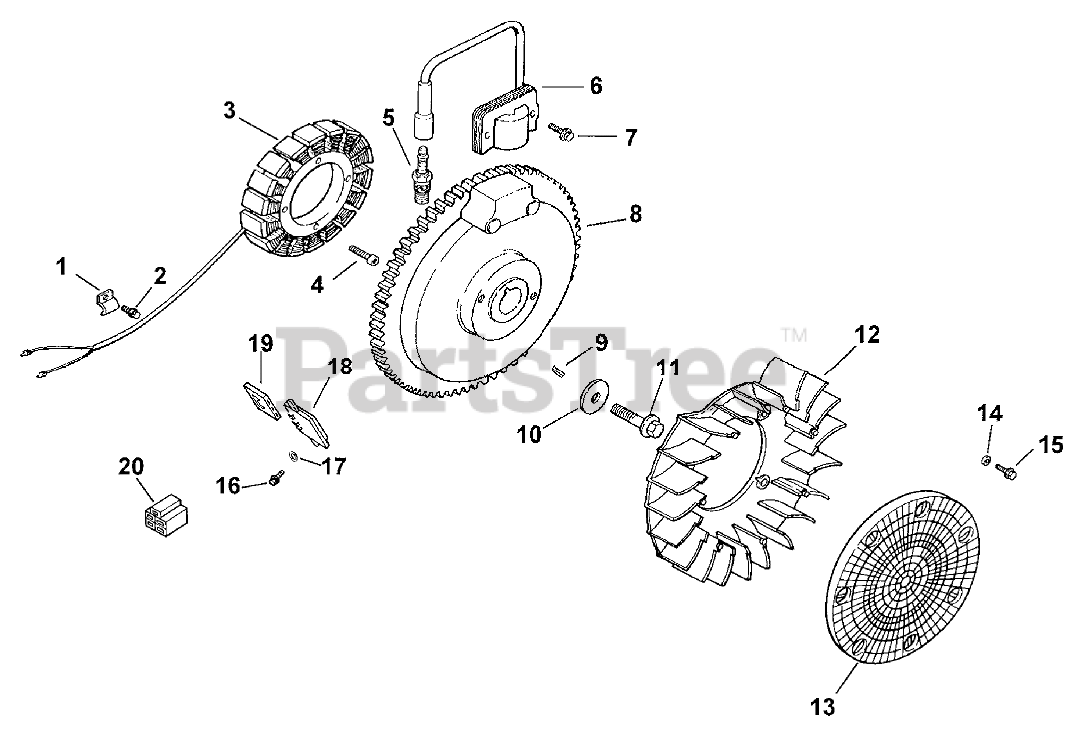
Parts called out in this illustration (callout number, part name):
1	Clip
2	Screw
3	Kit, 15 amp stator (Includes
4	Screw
5	Plug-Spark
6	Module, ignition
7	Screw
8	Flywheel
9	Key
10	Washer
11	Screw
12	Fan
13	Screen-Grass
14	Spacer
15	Screw
16	Screw
17	Washer
18	Rectifier-regulator
19	Connector
20	Connector
